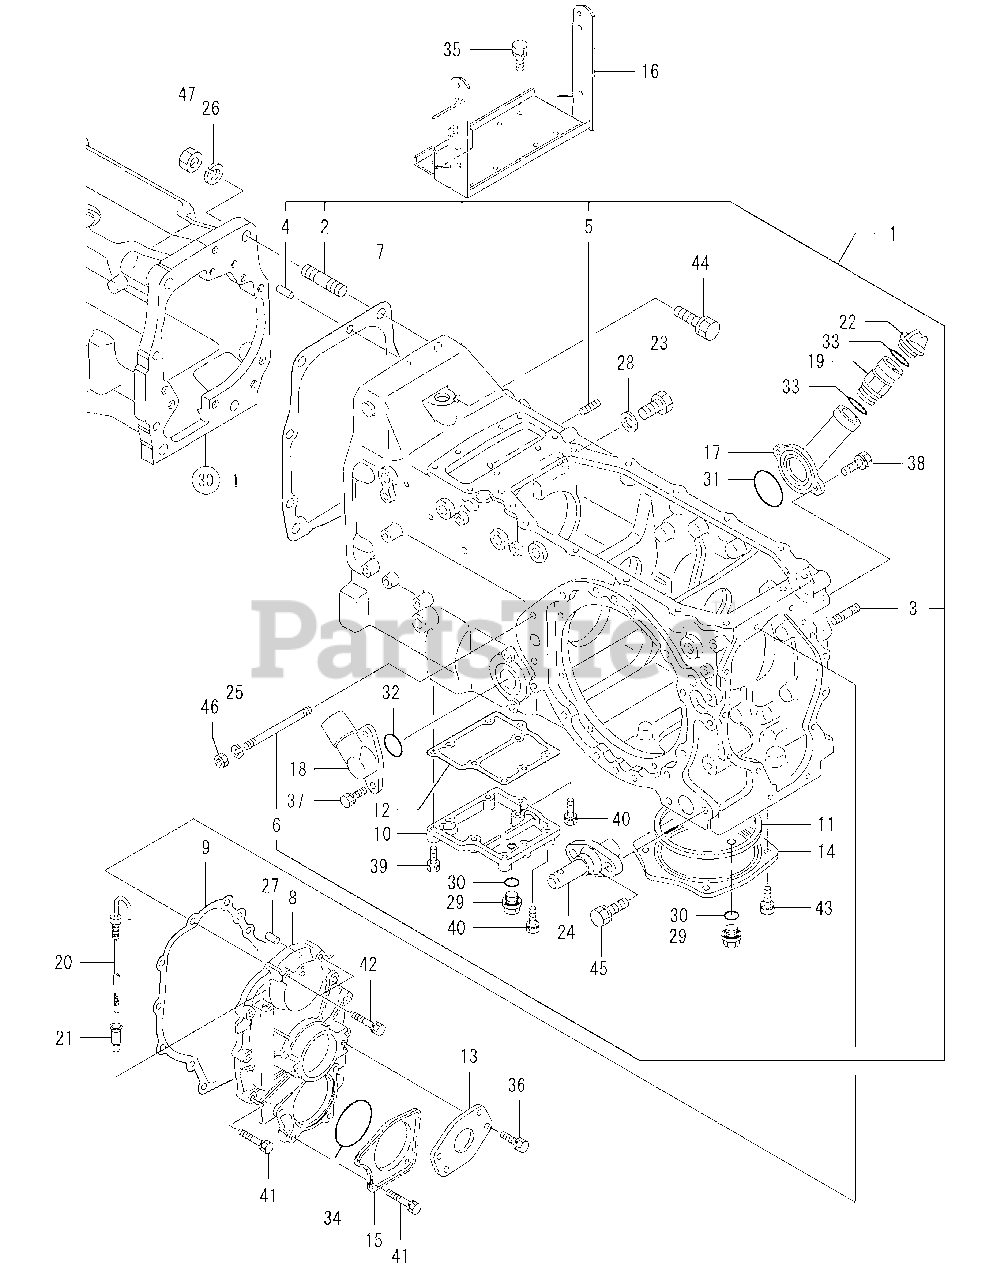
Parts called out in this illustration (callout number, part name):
1	HOUSING,TRANSMISSION
4	PARALLEL PIN 10X 18
6	STUD M10X 90 PLATED
7	PACKING, MISSION
10	COVER, FRONT DRIVE
11	COUPLING 140=3
13	PLATE, OIL SEAL
20	GAUGE COMP,OIL
21	GUIDE, DIPSTICK
23	PLUG 3/4-16UNF
24	PIN, LOWER LINK
25	SPRING WASHER 10
26	SPRING WASHER 16
27	PARALLEL PIN 10X 18
30	O-RING 1A P-16.0
31	O-RING 1A P-50.0
34	O-RING 1A G-75.0
35	BOLT W/WASHER M8X16
36	BOLT W/WASHER M8X16
37	BOLT W/WASHER M8X20
38	BOLT W/WASHER M8X20
43	BOLT W/WASHER M10X25
45	BOLT W/WASHER M14X35
